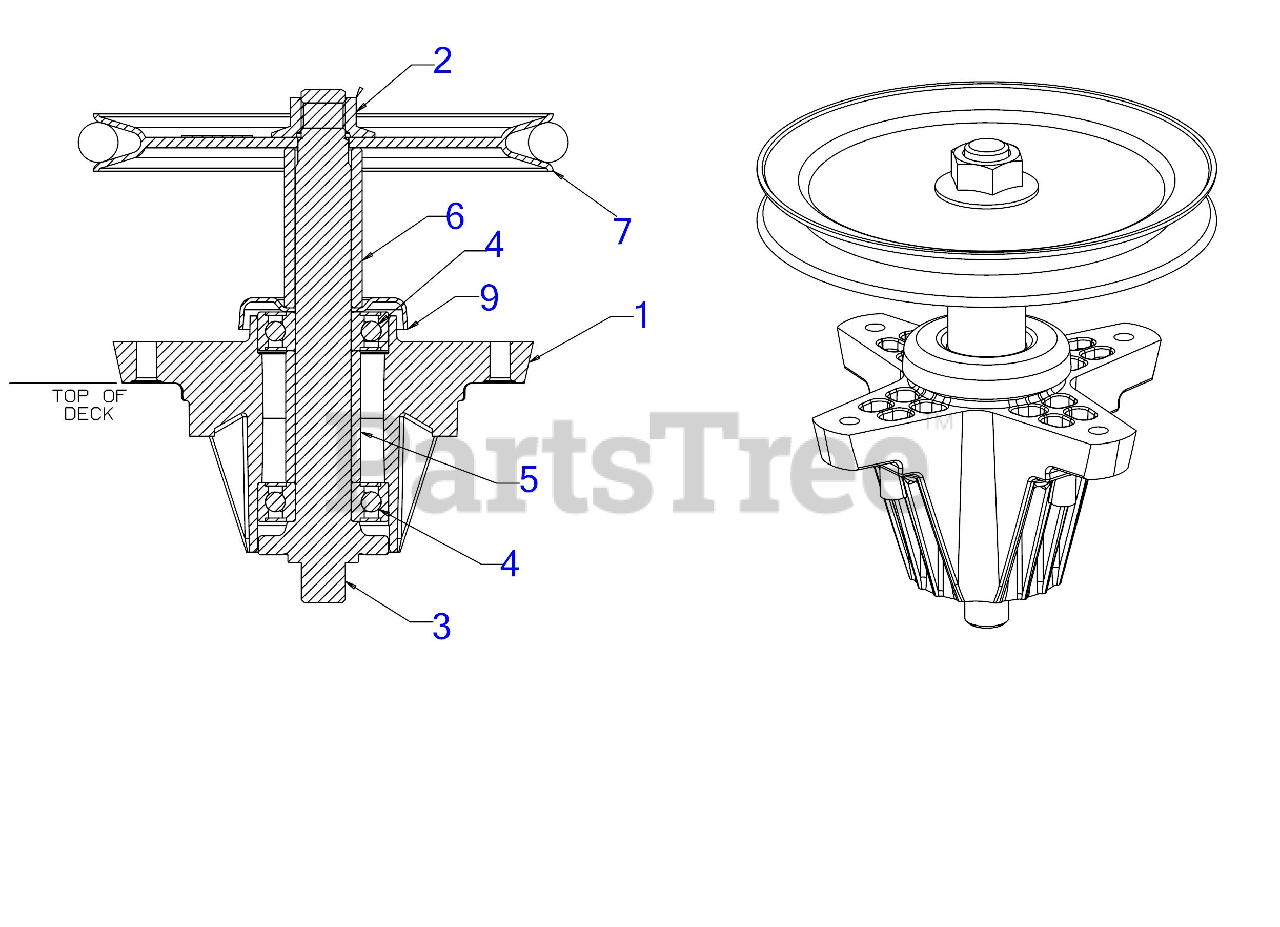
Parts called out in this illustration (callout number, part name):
1	DECK SPINDLE HOUSING
2	FLANGE NUT 5/8-18
3	SPINDLE SHAFT
4	BALL BEARING
5	SPACER- .792 x 1.060 x 1.860
6	SPACER .80 x 1.10 x 2.26 LG
7	DECK PULLEY 6.93"
9	SHIELD-BRG DECK
